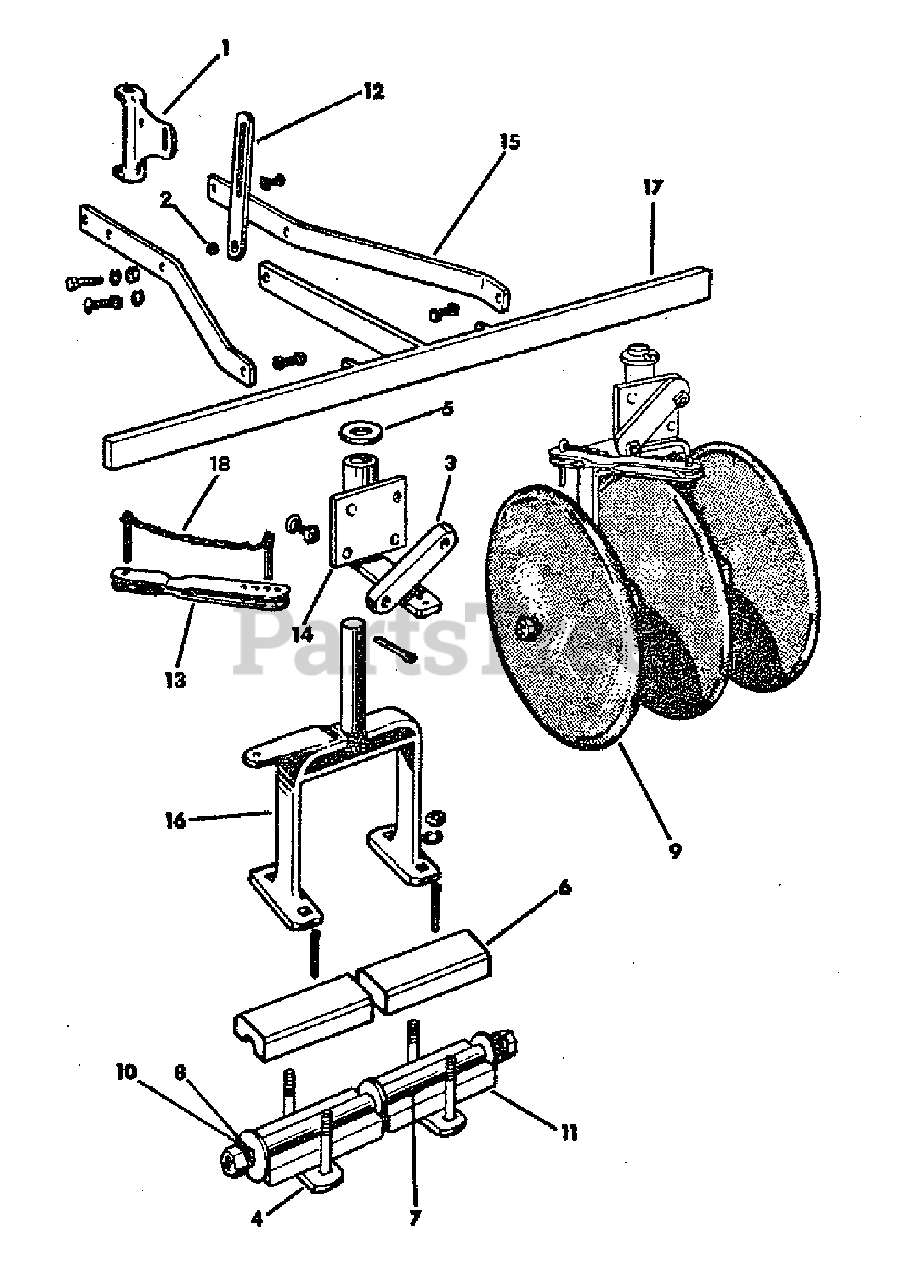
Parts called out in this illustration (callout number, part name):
1	END, Draw Bar
2	SPACER, Adjustment Link
3	CLIP, Clamp
4	CLIP, Bearing
5	POST WASHER
6	BLOCK, Upper Bearing
7	DISC SPACER
8	AXLE, 8 Disc
9	BLADE, 12" Disc
10	AXLE, 6 Disc
11	BLOCK, Lower Bearing
12	LINK, Tilt Adjusting
13	STRAP ASSEMBLY, Angle Adjusting
14	CLAMP ASSEMBLY
16	ARCH ASSEMBLY
17	BAR ASSEMBLY, Cross
